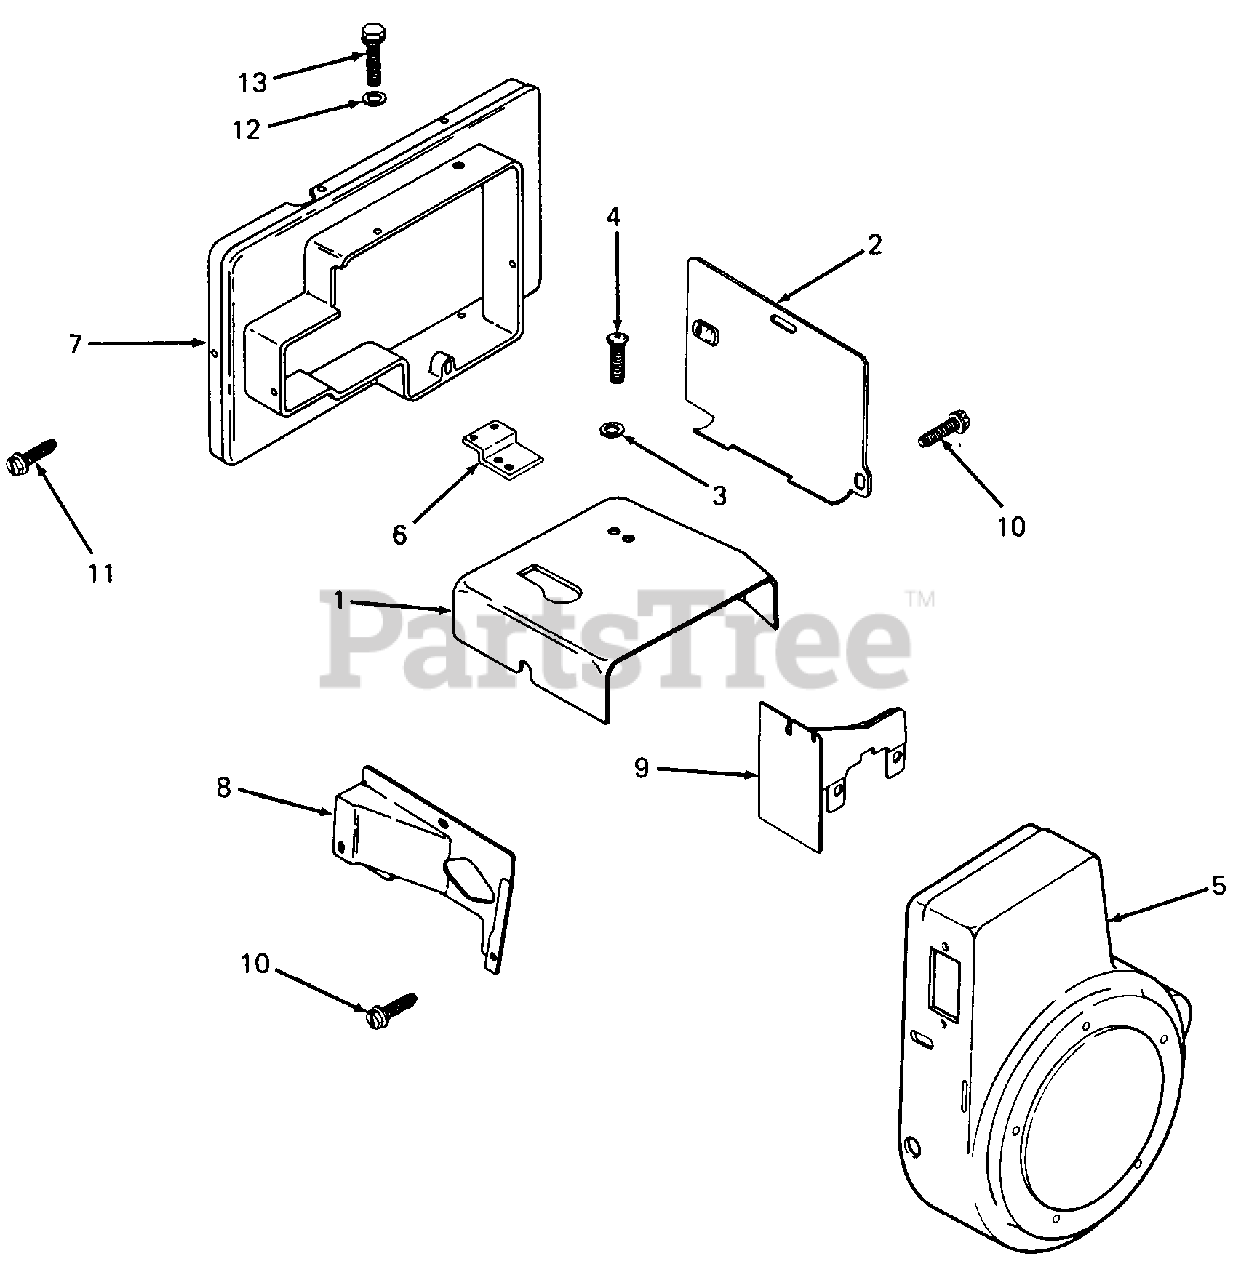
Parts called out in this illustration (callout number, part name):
1	Baffle, Head
2	Baffle, Cylinder
3	Washer, Plain, 1/4
4	Screw, Pozidriv T.H., 1/4-20 X 1/2 Lg
5	Housing, Blower
6	Bracket, Duct
7	Kit, Duct
8	Baffle, Side Air
9	Baffle, Inner
10	Screw, Hex Wash Hd, 1/4-20 X 5/8 Lg
11	Screw, Hex Wash Hd, #10-32 X 7/16 Lg
12	Washer, Plain, 1/4
13	Screw, HC Sems, 5/16-18 X 1.25 Lg
